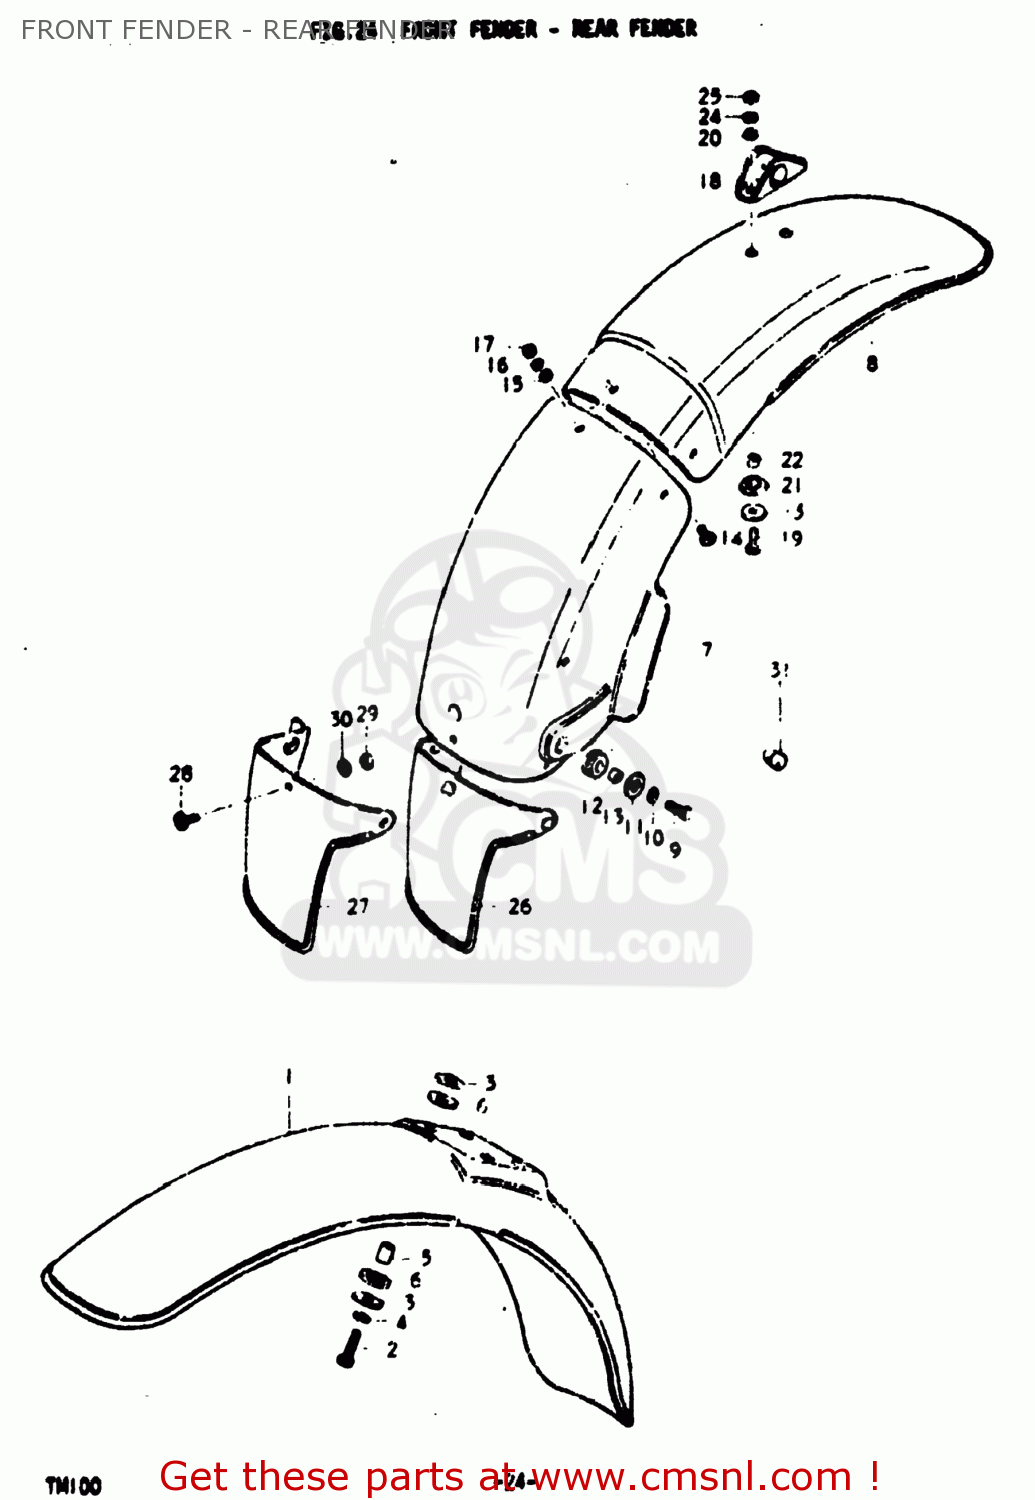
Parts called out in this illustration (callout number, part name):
1	FENDER,FRONT
2	BOLT
3	WASHER (6.5X24X1.2)
4	LOCK WASHER
5	SPACER (6.5X10.5X13.5)
6	CUSHION
7	FENDER,REAR
8	FENDER,REAR
9	BOLT
10	LOCK WASHER
11	WASHER (6.5X20X1.2)
12	CUSHION
13	SPACER(6.1X9X7.5)
14	SCREW
15	WASHER 5MM
16	LOCK WASHER
17	NUT
18	REINFORCEMENT,REAR FENDER
19	BOLT(6X18)
20	WASHER
21	CUSHION
22	SPACER
23	WASHER (6.5X20X1.2)
24	LOCK WASHER
25	NUT
26	STAY SET,MUD FLAP,REAR
27	MUD GUARD,REAR FENDER
28	SCREW
29	NUT
30	WASHER
31	CUSHION
